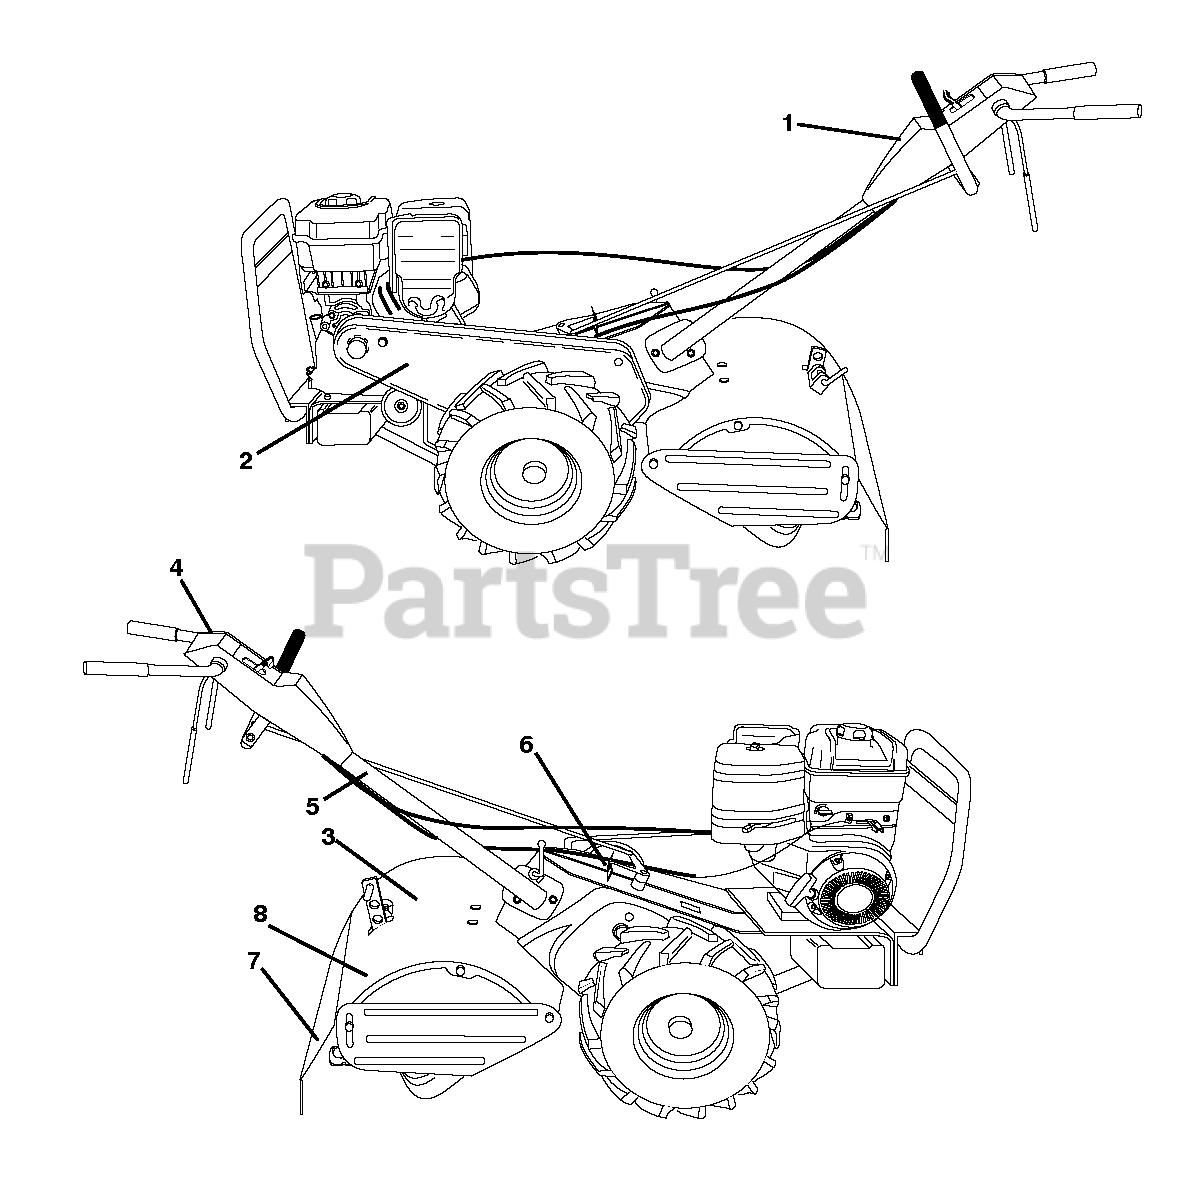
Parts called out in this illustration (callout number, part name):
1	Decal, Logo
2	RP.DECAL.BADGE.170MM.TEXTLOGO
3	Decal, Tine Shield
4	Decal, Console INS CRT
5	DECAL TI (2 2)
6	DECAL, SHIFT INDICATOR
7	DECAL TI
8	DECAL.WARNING.SHLD.ENG/FR
